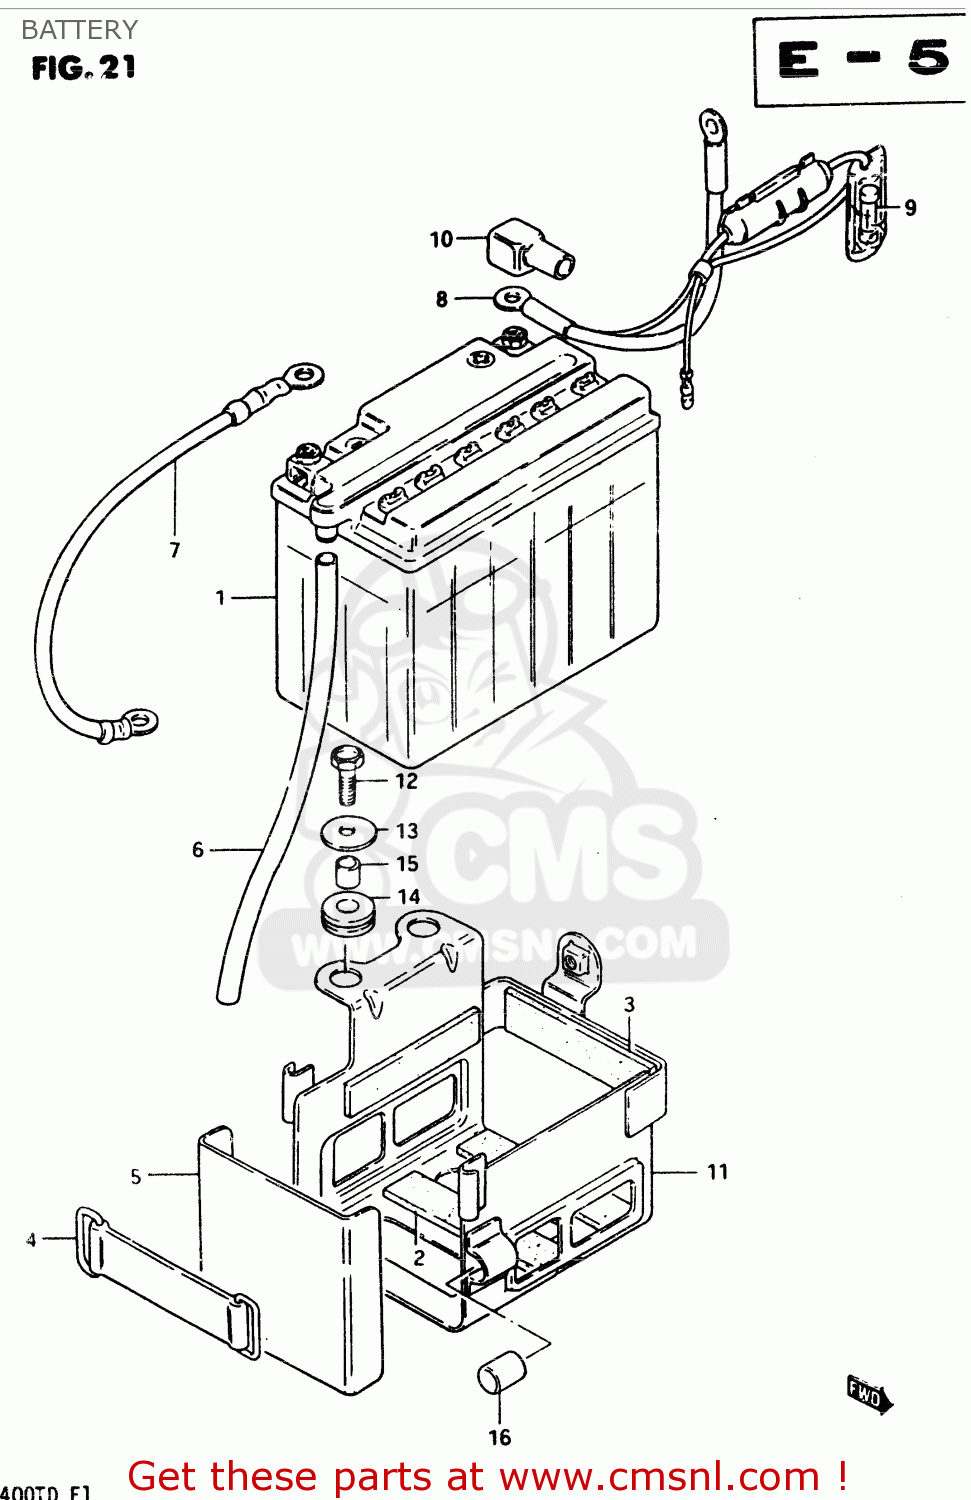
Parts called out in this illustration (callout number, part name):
1	BATTERY(YB12B-B2,12V11.6A)
2	PROTECTOR(20X90)X4
3	PROTECTOR,20X9
4	BAND
5	COVER,BATTERY
6	HOSE,BATTERY EXHAUST
7	LEAD WIRE,BATTERY(-)
8	FUSE CASE AND PLUS CABLE
9	FUSE(15A)
10	CAP,TERMINAL
11	HOLDER,BATTERY
12	BOLT
13	WASHER
14	CUSHION
15	SPACER (6.1X9X9)
16	CUSHION
